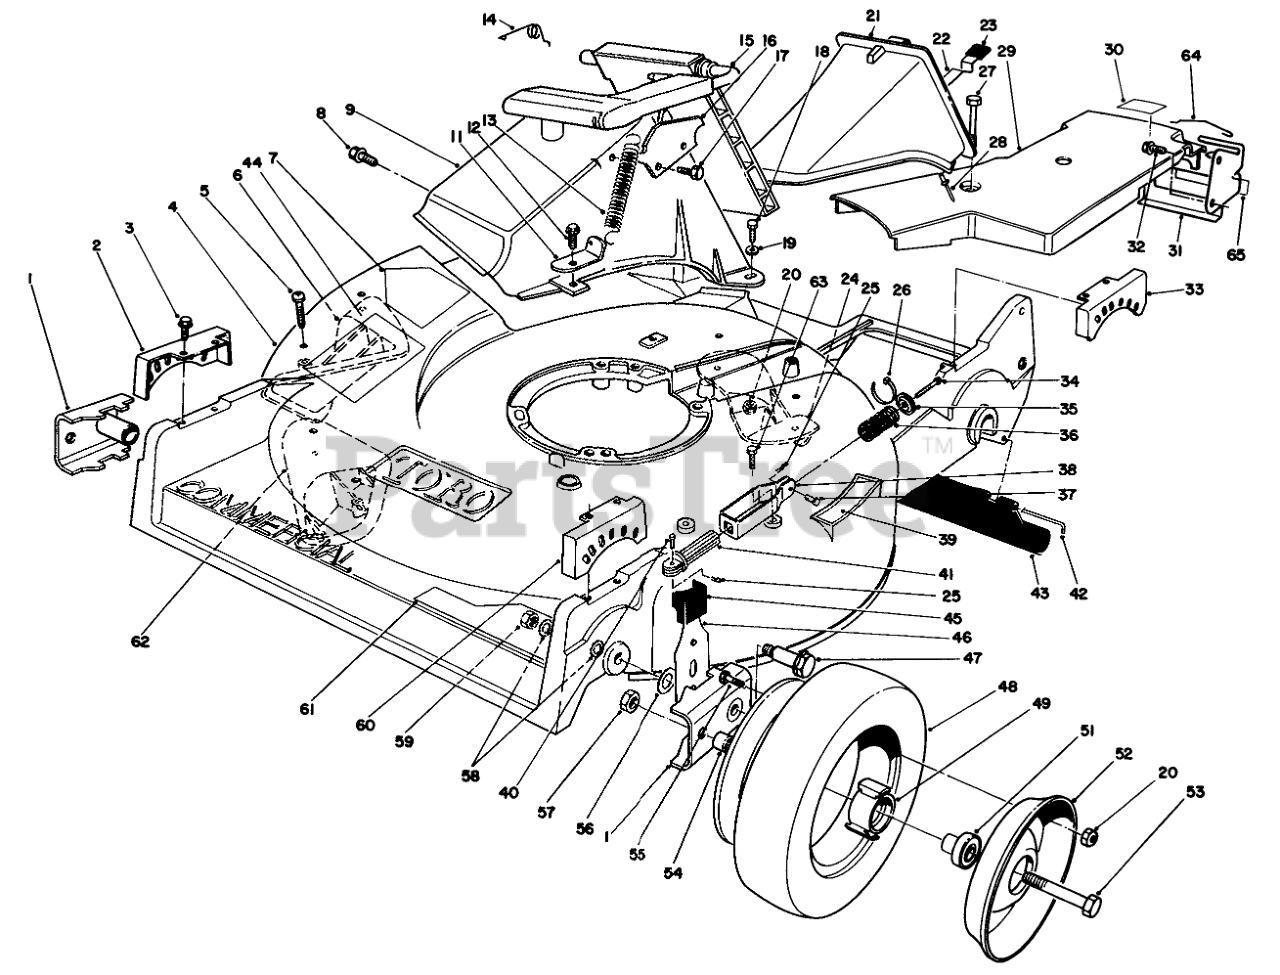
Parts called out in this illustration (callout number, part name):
1	ARM-PIVOT, FRONT
2	QUADRANT-FRONT, RH
3	SCREW-HWHTF
4	Housing-Commercial (Incl. Ref. #5-7, 24, &62)
5	SCREW-PPH
6	KICKER-RH
7	DECAL-DANGER
8	SCREW AND WASHER ASM
9	DISCHARGE TUNNEL
11	BRACKET-SPRING
12	SCREW-HWH
13	SPRING-DOOR
14	RETAINER-DOOR
15	DOOR ASSEMBLY
16	DOOR LATCH PLATE
17	SCREW-PLASTITE
18	SCREW-HH
19	WASHER-FLAT
20	NUT-LOCK, NI
21	Plug-Discharge (Incl. Ref. #22, 23, &28)
22	LATCH-PLUG, DISCHARGE
23	GRIP-LATCH
24	KICKER-REAR
25	PIN-COTTER
26	TIE-CABLE
27	SCREW-HHFTF
28	RIVET-HEAD, FLAT
29	COVER-BELT
30	LABEL-GREASE
31	BRACKET-ADJUSTMENT, TRACTION
32	SCREW-HWHTF
33	QUADRANT-REAR, LH
34	SCREW-HWHTF
35	RETAINER-SPRING
36	SPRING
37	PIN-CABLE
38	Bracket-Spring
39	STEP PAD DECAL
40	PIN-SPRING
41	GUIDE-SPRING
42	ROD-SHIELD
43	SHIELD-TRAILING
44	DECAL - DANGER, COVERS
45	KNOB-ARM
46	FRONT SPRING ARM ASM
47	BOLT-WHEEL
49	HUB-BEARING
51	Bearing-Wheel
52	Wheel-Half
53	SCREW-HH
54	SPACER-WHEEL
55	SCREW-HH
56	WASHER-THRUST
57	NUT-LOCK, CONE
58	WASHER
59	NUT-LOCK
60	QUADRANT-FRONT, LH
61	DECAL - RECYCLER
62	KICKER-FRONT
63	SCREW-HH
64	RETAINER-CABLE
65	DECAL-POSITION, GEAR
